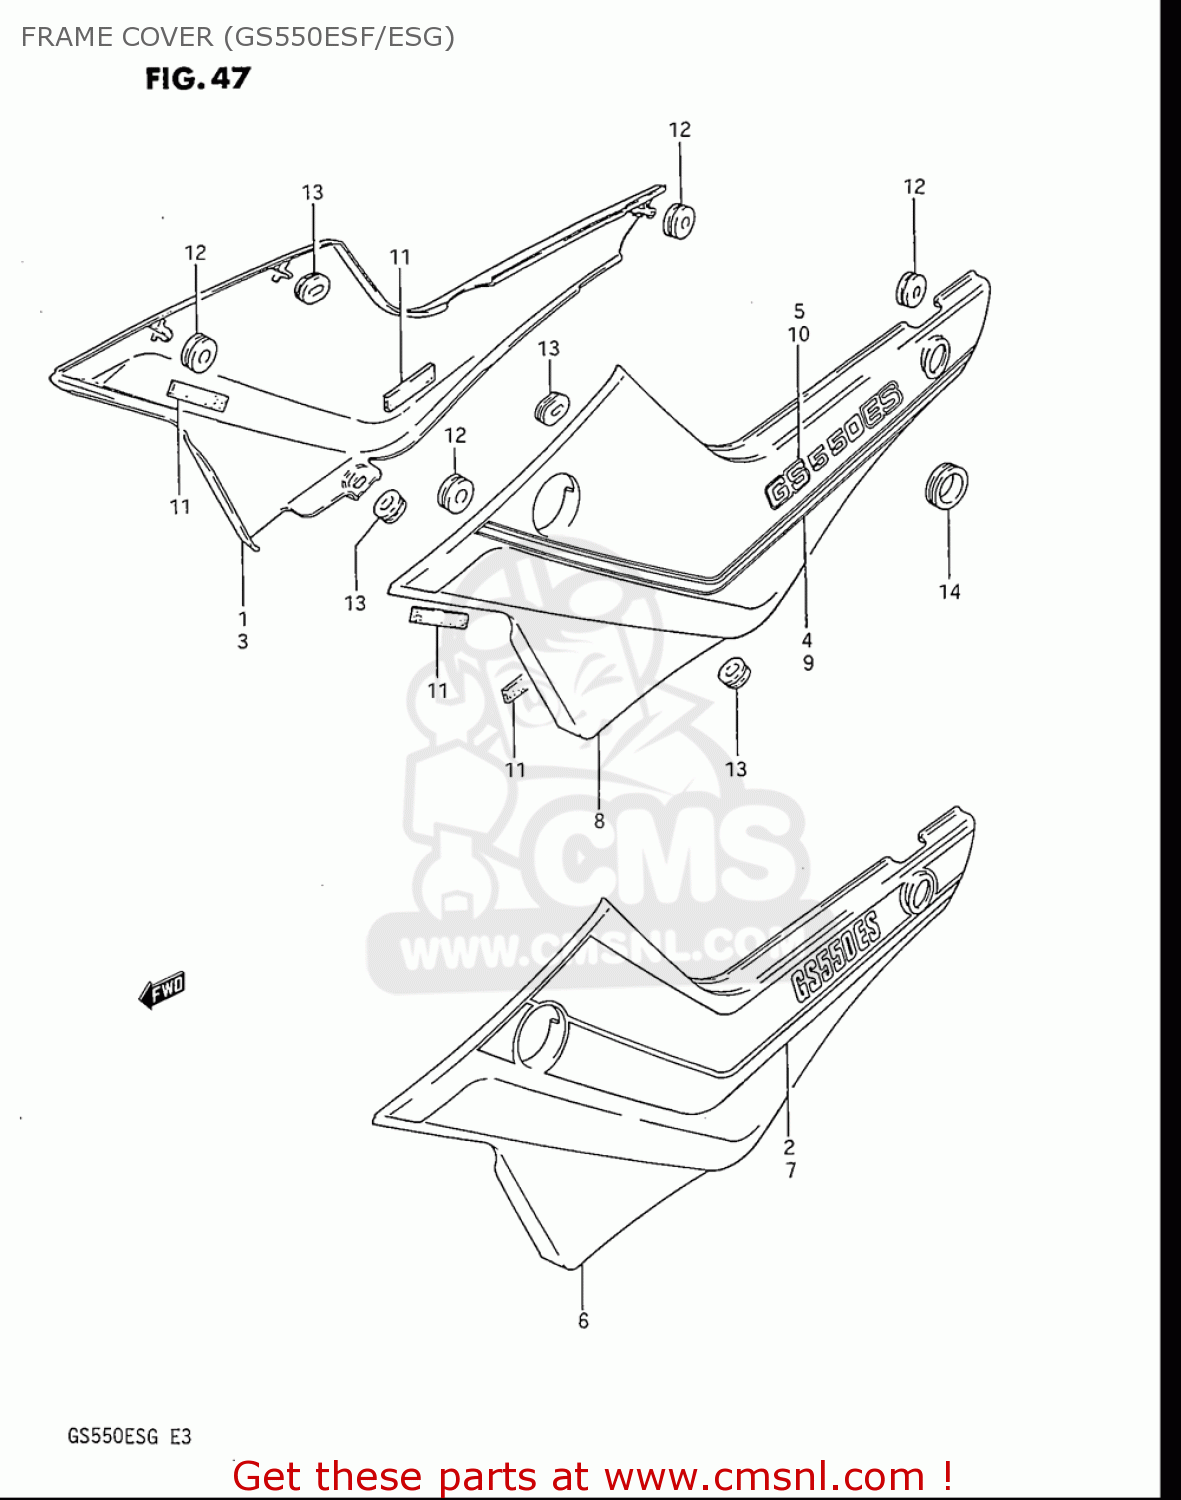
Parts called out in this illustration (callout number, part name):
1	COVER,FRAME,R
3	COVER,FRAME,R
6	COVER,FRAME,L
7	TAPE SET,FRAME COVER
8	COVER,FRAME,L
11	RUBBER,FRAME COVER
12	CUSHION
13	CUSHION
14	GROMMET,SEAT LOCK HOLE
